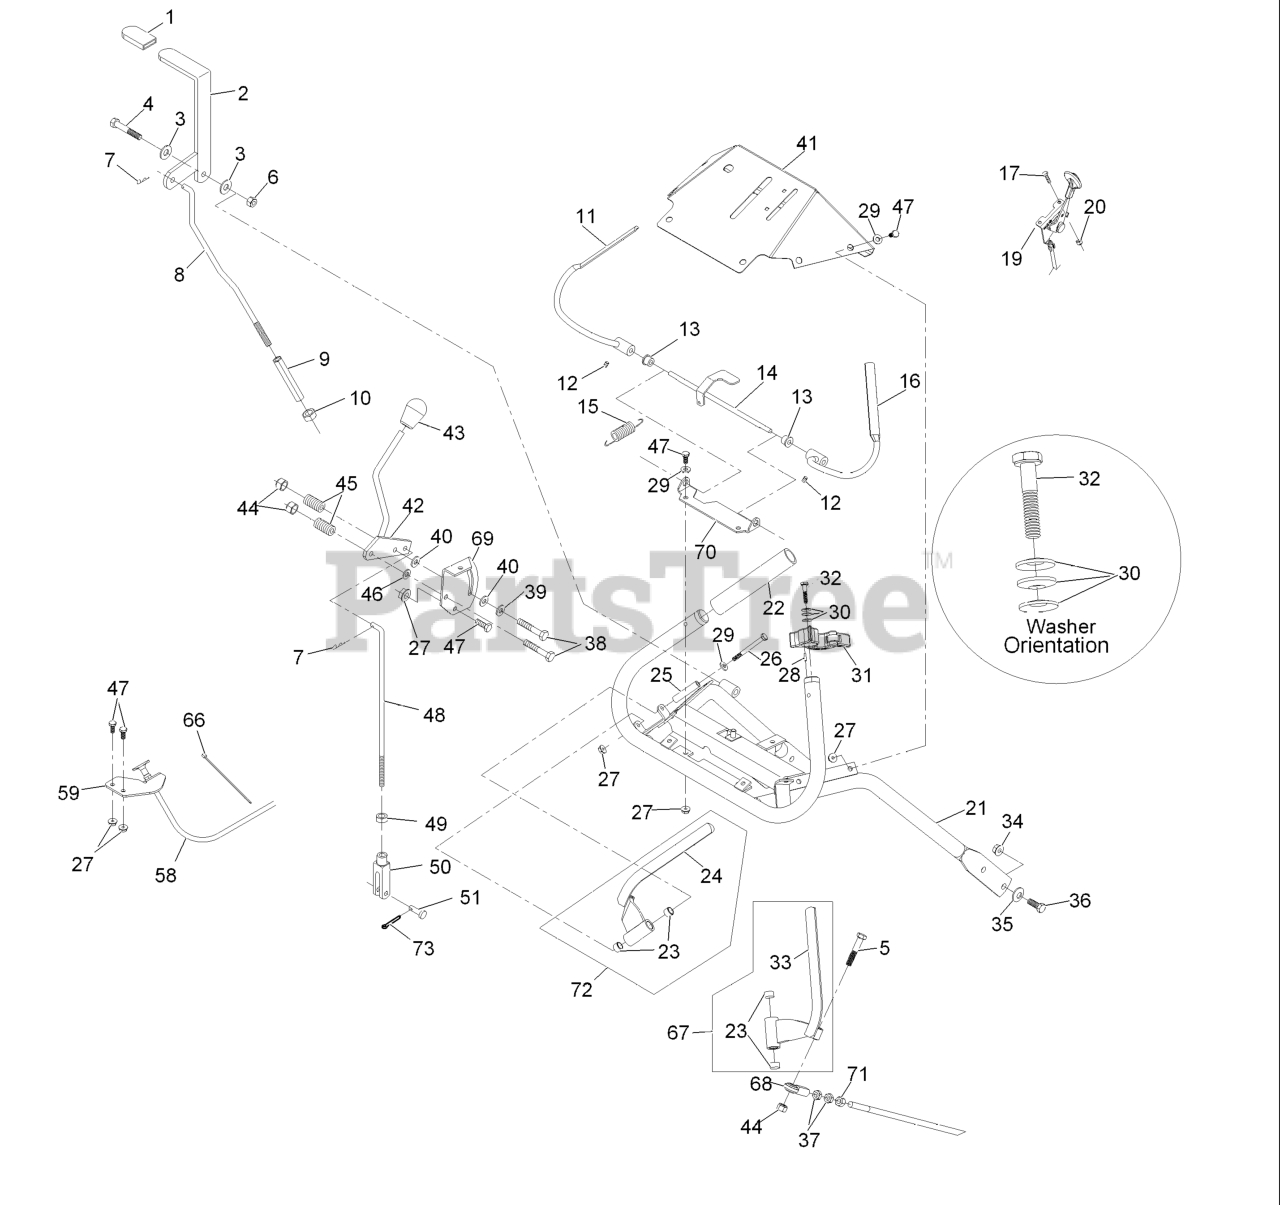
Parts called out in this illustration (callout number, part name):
1	GRIP-LEVER
3	WASHER-FLAT
4	SCREW-HH
5	SCREW-HH
6	NUT-LOCK, NI
7	PIN-COTTER
8	LINK,BLADE ENGAGE (PLTD)
9	TURNBUCKLE
10	NUT-HEX
11	WLD,LH OPC LEVER
12	SCREW-SET
13	BUSHING-NYLON
14	WLD,OPC LEVER AXLE
15	SPRING-EXTENSION
16	WLD,RH OPC LEVER
17	BOLT-CARR
19	CONTROL, THROTTLE
20	NUT-LOCK, NI
21	WLD,UPPER ECS HANDLE
22	GRIP-BAR, HANDLE
23	BUSHING-SLEEVE
24	Lever, Drive Lh
25	BUSHING-LEVER, DRIVE
26	SCREW-HH
29	WASHER-FLAT
30	WASHER-SPRING
31	ASM,LATCH RH THUMB
32	SCREW-HH
33	Lever, Drive Rh
34	NUT-HHF, WHIZ
35	WASHER-BELLEVILLE
36	SCREW-HH
37	NUT-HJ
38	SCREW-HH
39	WASHER-FRICTION
40	WASHER-FRICTION
41	ASM,CONSOLE W/DECALS
43	KNOB, FE.LCKG. BLACK
44	NUT-LOCK, NI
45	SPRING-COMPRESSION
46	WASHER-PLAIN
47	SCREW-HH
48	ROD,SPEED CONTROL
49	NUT-JAM
50	YOKE-ADJUSTABLE
51	PIN-CLEVIS
58	CABLE-CHOKE
59	BRACKET-CABLE, CHOKE
66	TIE-CABLE
67	DRIVE LEVER-ASM, RH
68	JOINT-BALL, END
69	BRACKET,SHIFTER SLIDE (PL
70	BRACKET,OPC AXLE
71	NUT-HEX
72	DRIVE LEVER-ASM, LH
73	PIN-COTTER
